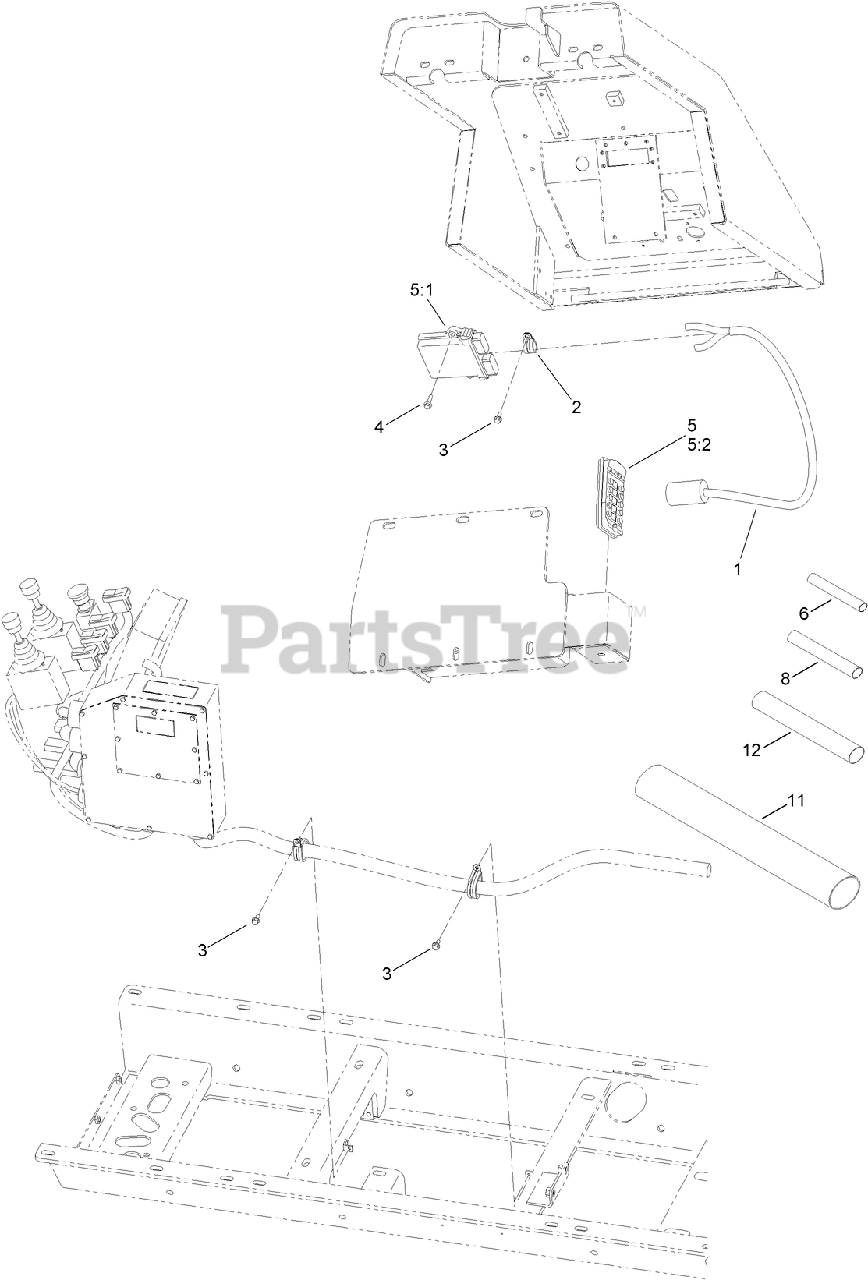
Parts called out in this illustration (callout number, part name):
1	CABLE ASM
2	CLAMP
3	SCREW-HHF
4	SCREW-HHF
5	OMNEX RADIO KIT
5:1	RECEIVER-BULLDOG
5:2	TRANSMITTER
6	TUBING-SHRINK, HEAT (3/8IN ID)
8	TUBING-SHRINK, HEAT (3/4IN ID)
11	TUBING-SHRINK, HEAT (3IN ID)
12	TUBING-SHRINK, HEAT (1.5IN ID)
